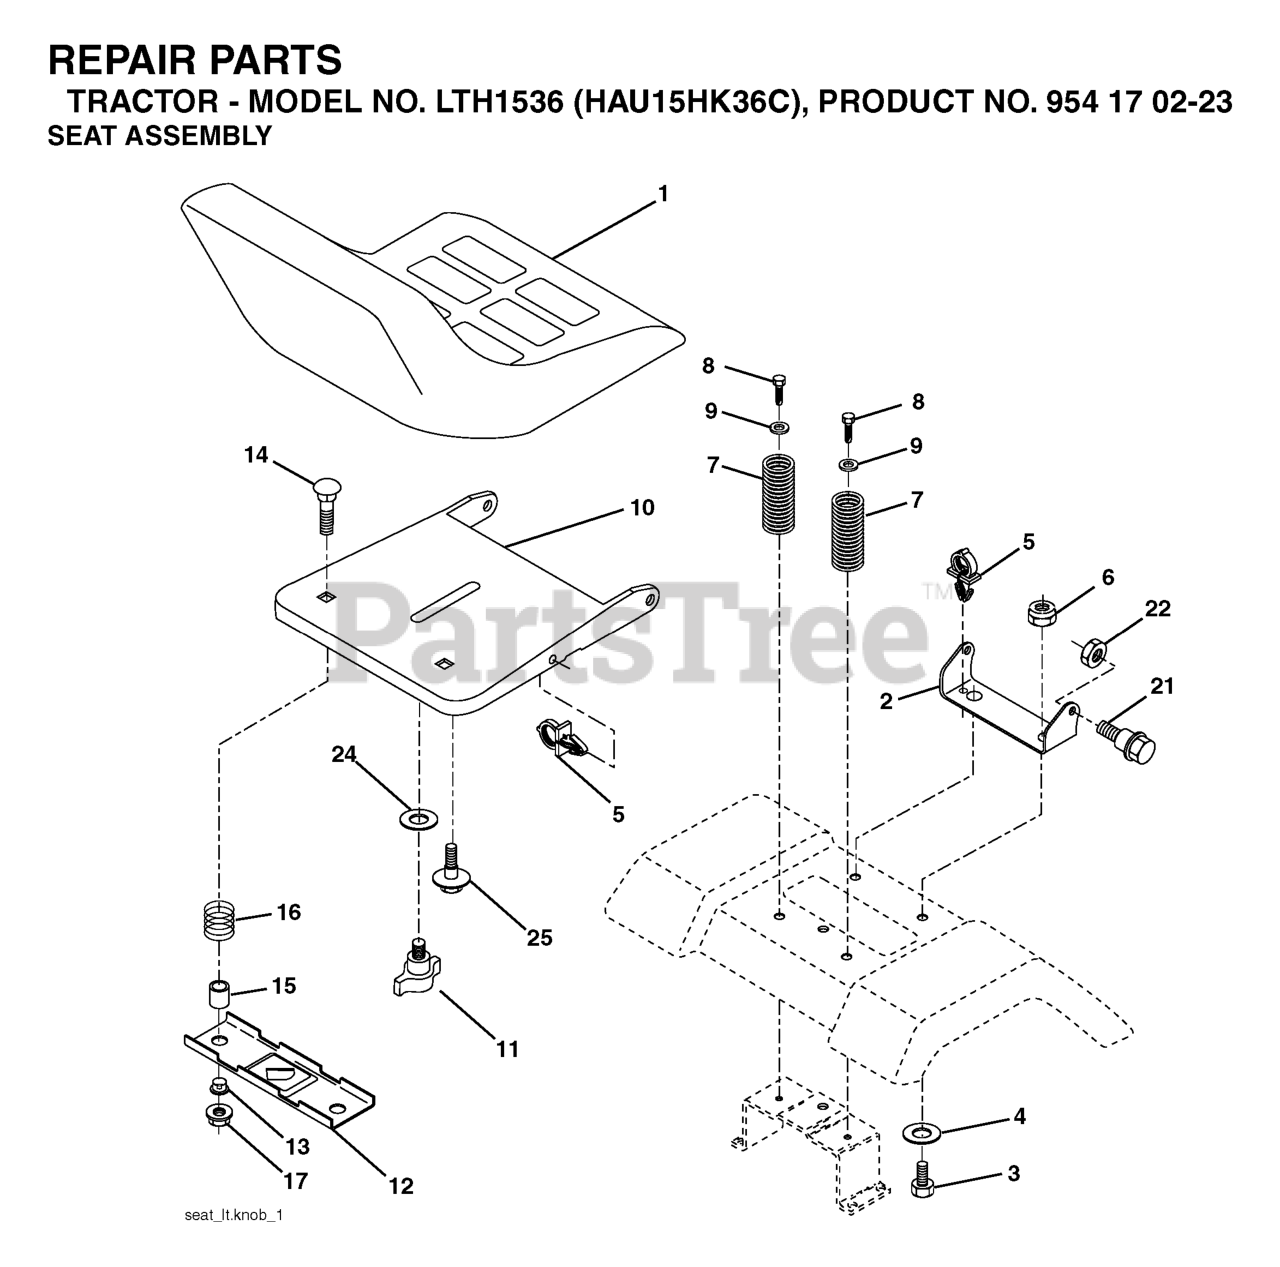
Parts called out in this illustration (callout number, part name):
1	RP SEAT
2	SEAT PIVOT BRKT
3	BOLT, HEX 3/8-16X1
6	NUT
7	SPRING COMPRESSION
8	SCREW 3/8-16X1
9	WASHER
10	PAN SEAT
11	KNOB.SEAT.ADJ.WINGNUT
12	BRKT SWITCH
14	BOLT.ROUND.HEAD.SQUARE.NECK
15	SPACER SPLIT 28X.96
17	NUT T
21	BOLT.SHOULDER.5/16-18
22	NUT.71038.31-18.HEX.NYLOCK
25	BOLT,SHOULD
